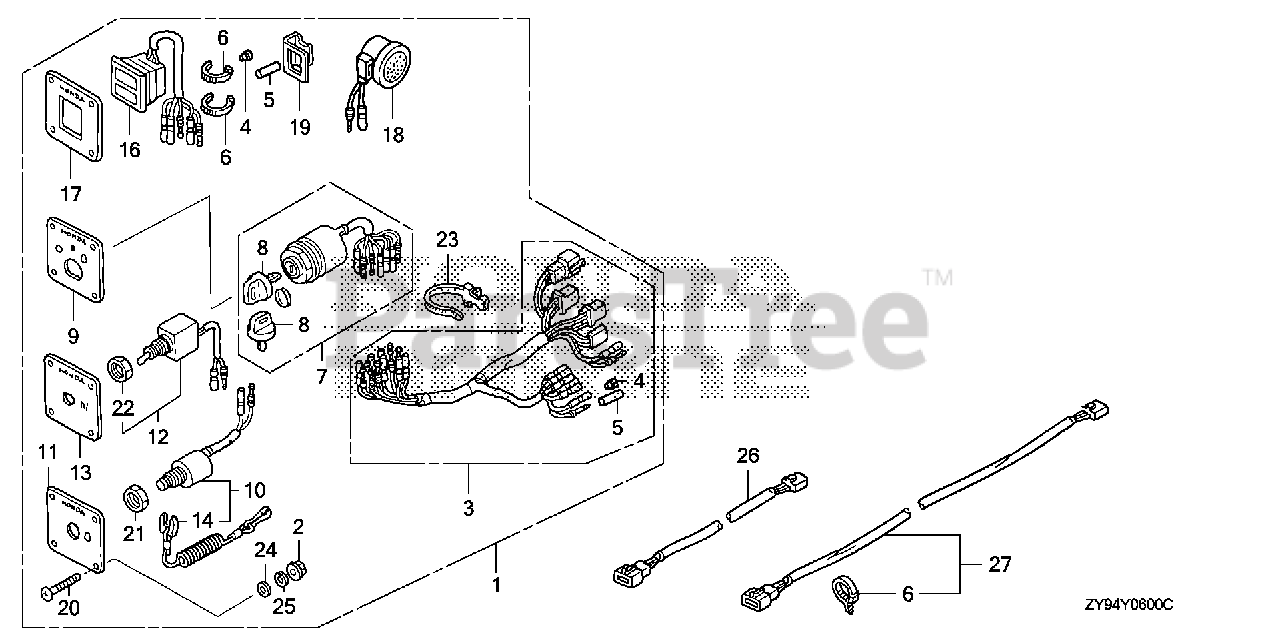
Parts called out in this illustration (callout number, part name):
1	PANEL KIT, CONTROL (2-LED) (A)
2	NUT, FLANGE (5MM)
3	HARNESS ASSY., SWITCH PANEL
4	PLUG, CONNECTOR (INNER)
5	PLUG, CONNECTOR (OUTER)
6	TIE, CABLE (2.4X92) (NATURAL)
7	SWITCH ASSY., COMBINATION
8	KEY ASSY., COMBINATION SWITCH (35100-ZV5-003 ONLY)
9	PANEL, SWITCH
10	SWITCH ASSY., EMERGENCY STOP
11	PANEL, EMERGENCY STOP SWITCH
12	SWITCH ASSY., SOLENOID
13	PANEL, SOLENOID
14	WIRE, EMERGENCY
16	LAMP ASSY., INDICATOR (2-LED)
17	PANEL, INDICATOR
18	BUZZER, WARNING
19	BRACKET, BUZZER
20	SCREW, PAN (5X40)
21	NUT, HEX. (16MM)
22	NUT, HEX. (12MM)
23	BAND, WIRE HARNESS (150MM) (NATURAL)
24	WASHER, PLAIN (5MM)
25	WASHER, SPRING (5MM)
26	CABLE ASSY., EXTENSION (3P 7FT) (FOR 2-LED)
27	CABLE ASSY., EXTENSION (3P 30FT) (FOR 2-LED)
